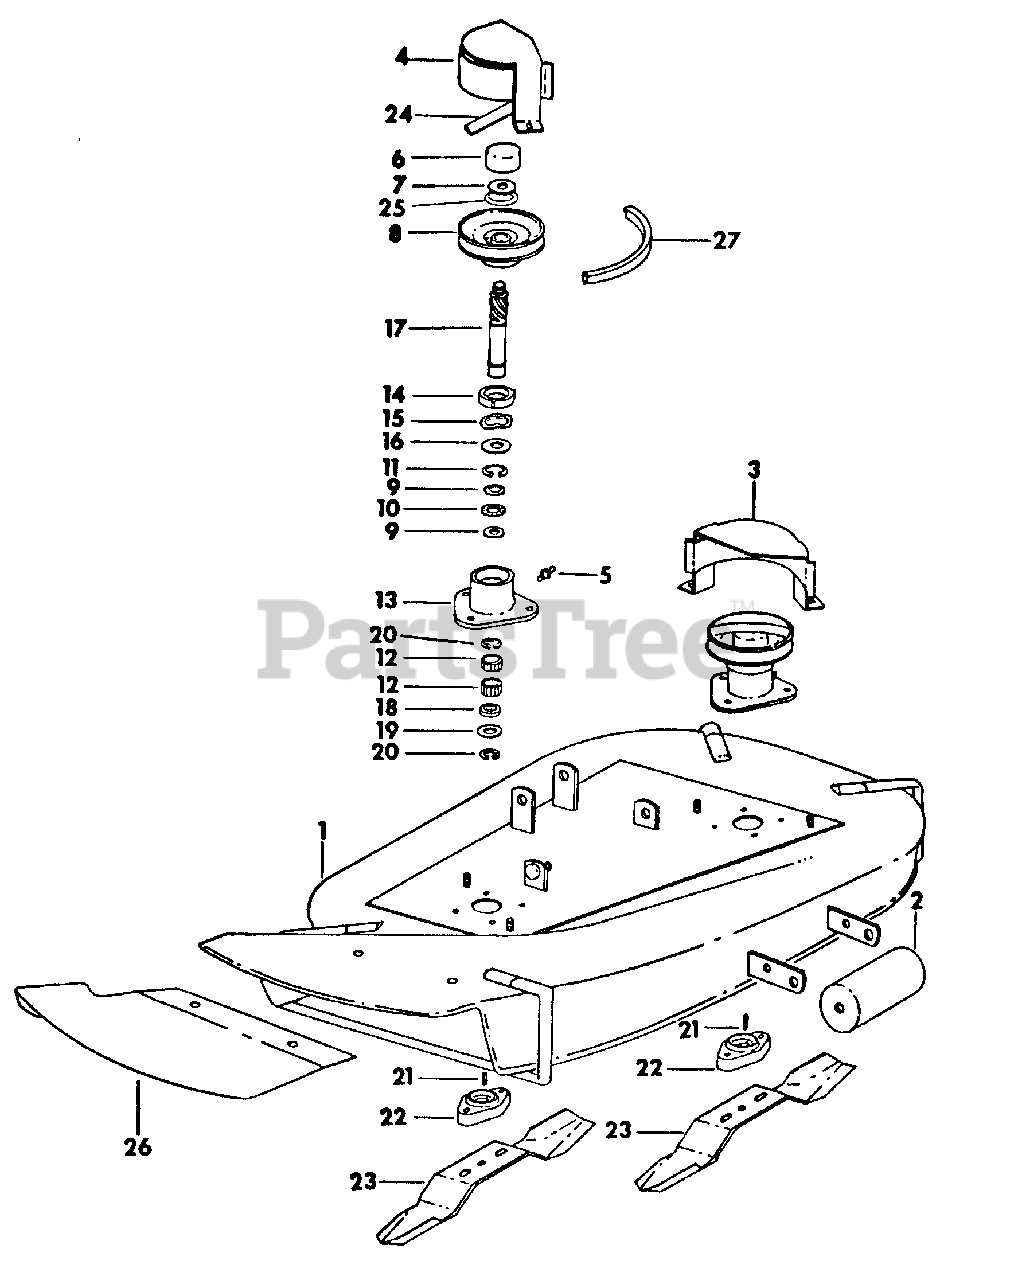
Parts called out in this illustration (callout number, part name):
1	Housing Assy, Mower
2	Roller, Front
5	Fitting, 3/16 Str Drive Lube
7	Washer, Special
8	Pulley, Outer
9	Race, Needle Thrust Bearing
10	Bearing, Needle
11	Ring, 1-1/4 Internal Retaining
12	Bearing, Needle
13	Housing, Blade Shaft
14	Brake, Insert
15	Washer, Wave
16	Washer, Stop
17	Shaft, Blade
18	Seal, Oil
19	Washer, Thrust
20	Ring, 3/4 External Retaining
21	Key, 3/16 X 1/2 Sq Parallel
22	Adapter, Blade
23	Blade, 36 Inch Mower
24	Spring, Cap Retainer
25	O-Ring, 1-13/16 X 2 X 3/32
26	Package, 36 Inch Mower Deflector
27	Belt, Mower Drive
